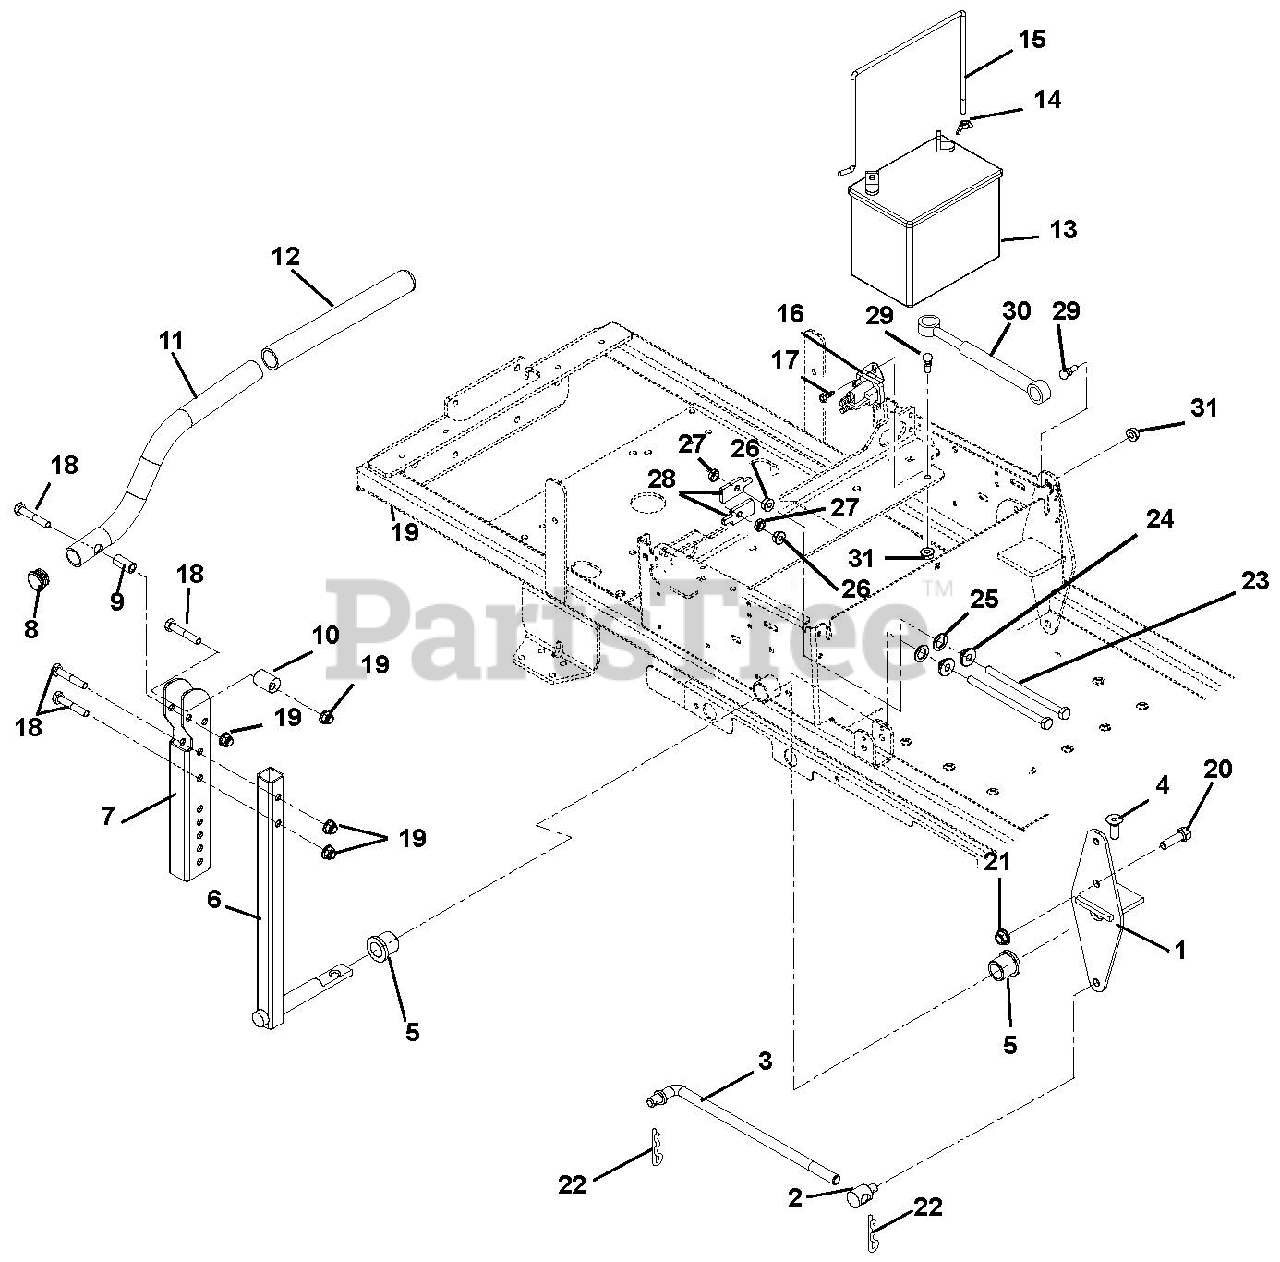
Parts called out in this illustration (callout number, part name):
1	CONTROL LINK WELDMENT
2	PIVOT, ROD (TRUNNION ) .50
3	LINK,WIREFORM
4	BOLT, 3/8-16X1 FSHCS PLN
5	BUSHING-1"X.75"X1"
6	WELDMENT, CONTROL ARM
7	CHANNEL, UPPER HANDLEBAR
8	CAPLUG, HANDLEBAR
9	BSHG, SPCR .330X.500X1.01 PM
10	BSHG,ECCEN .328X.750X1.01 PM
11	HANDLE BAR
12	GRIP - HANDLEBAR
14	NUT-LK WING .250-20 YWZC
15	BATTERY ROD
16	SOLENOID, HP RTV
17	@SCR-TAP .25-20X.37 HWH YWZ TR
18	@BLT-HEX .31-18X1.75 GR5 YWZC
19	@NUT-LK-NYL-FLG .31-18 YWZC
20	@BLT-HEX .38-16X1.25 GR5 YWZC
21	NUT-HEX-JAM .375-16 YWZC
22	PIN-HAIR INT .08X.18X1.18 YWZC
23	BLT-HEX,5/16-18X5 G2 HH YWZC
24	BSHG-FLG .32X.500X.344X.880
25	WSHR-FL-STL .52X.827X.062 YWZC
26	@NUT-SPNLK-FLG .312-18 YWZC
27	NUT- JAM .312-18 YWZC
28	STOP TAB
29	STUD- BALL
30	DAMPER, CONTROL
31	@NUT-LK-TOP-FLG .31-18 YWZC
